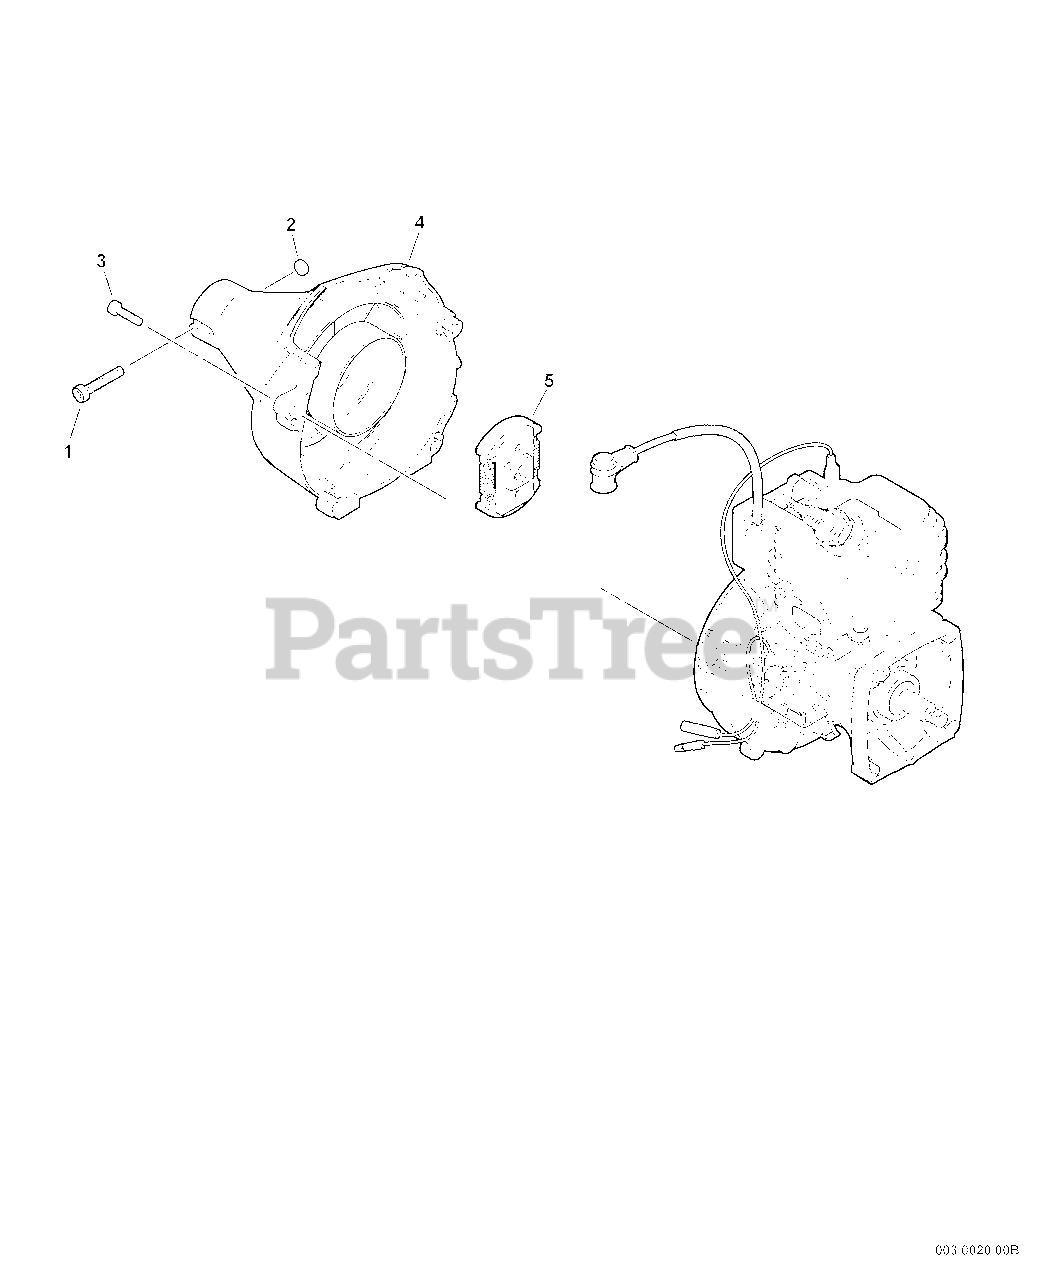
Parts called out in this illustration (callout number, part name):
1	BOLT, TORX 5×25
2	NUT M5
3	BOLT, TORX 4×16
4	FAN CASE ASSY
5	CLUTCH ASSY
